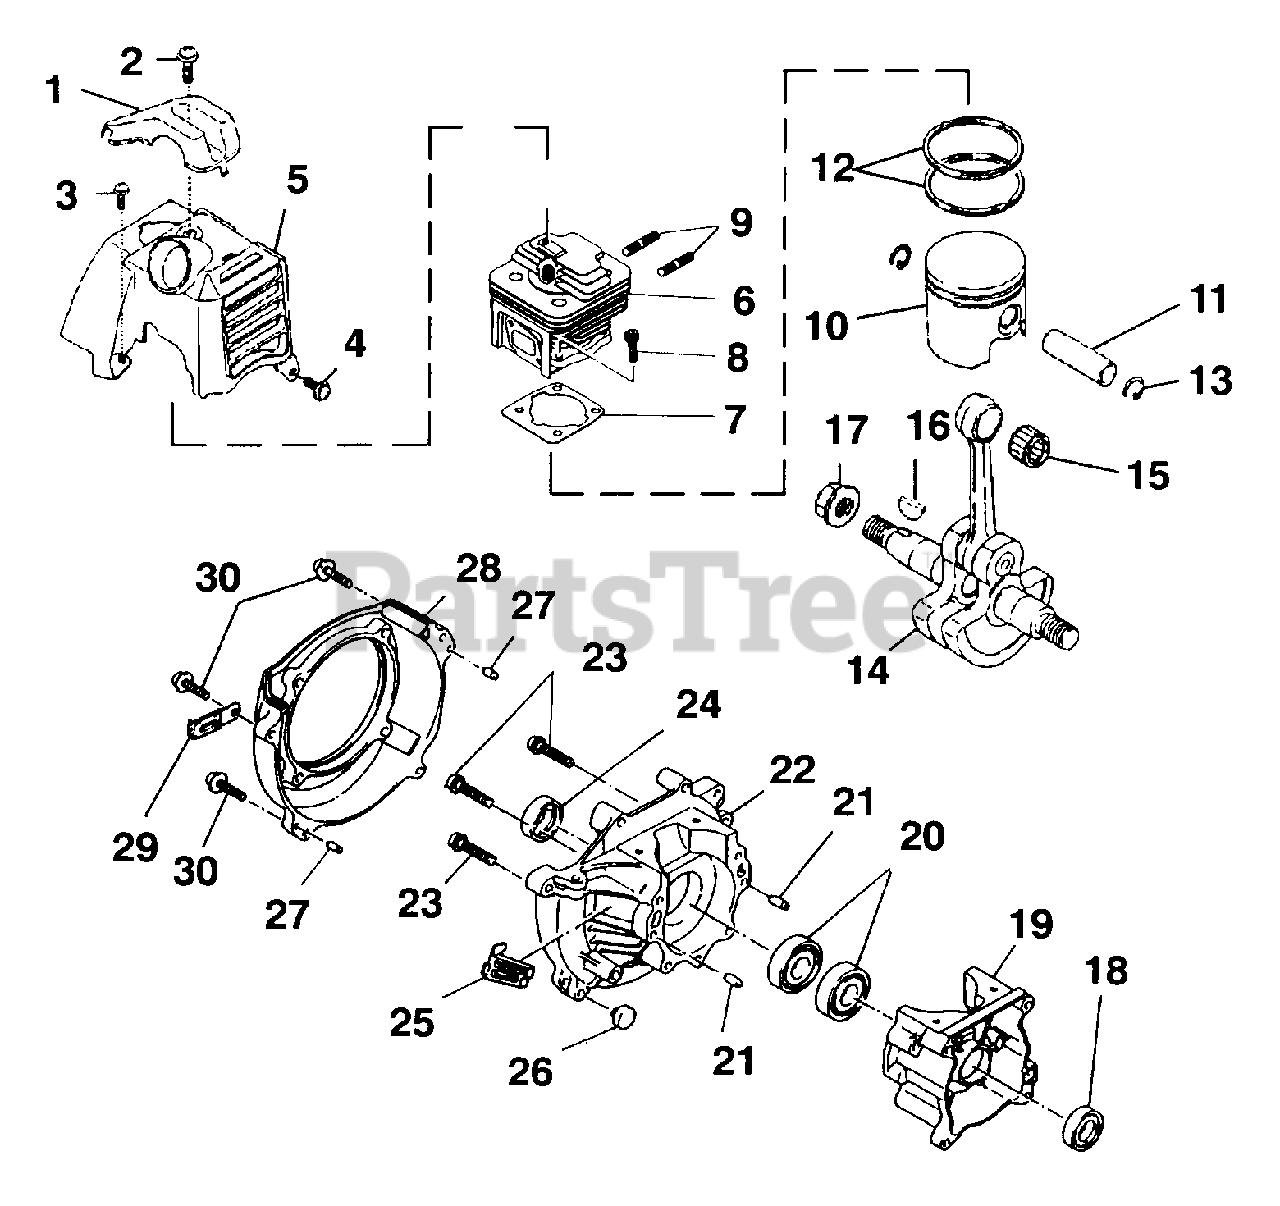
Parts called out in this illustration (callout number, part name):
1	Plug Guard
2	Screw & Washer
3	Screw & Washer
4	Screw & Washer
5	Top Cover
7	Gasket, Cylinder
8	Bolt & Washer
10	Piston Assembly
11	Pin, Piston
12	Ring, Piston
13	Clip, Piston Pin
14	Crankshaft
15	Needle Bearing
16	Woodruff Key
17	Nut
18	Oil Seal
19	Case, Starter
20	Ball Bearing
21	Dowel Pin
22	Case, Drive
23	Screw & Washer
24	Oil Seal
25	Cover, Crankcase
26	Pad, Fuel Tank
27	Dowel Pin
28	Case,Fan
30	Screw & Washer
